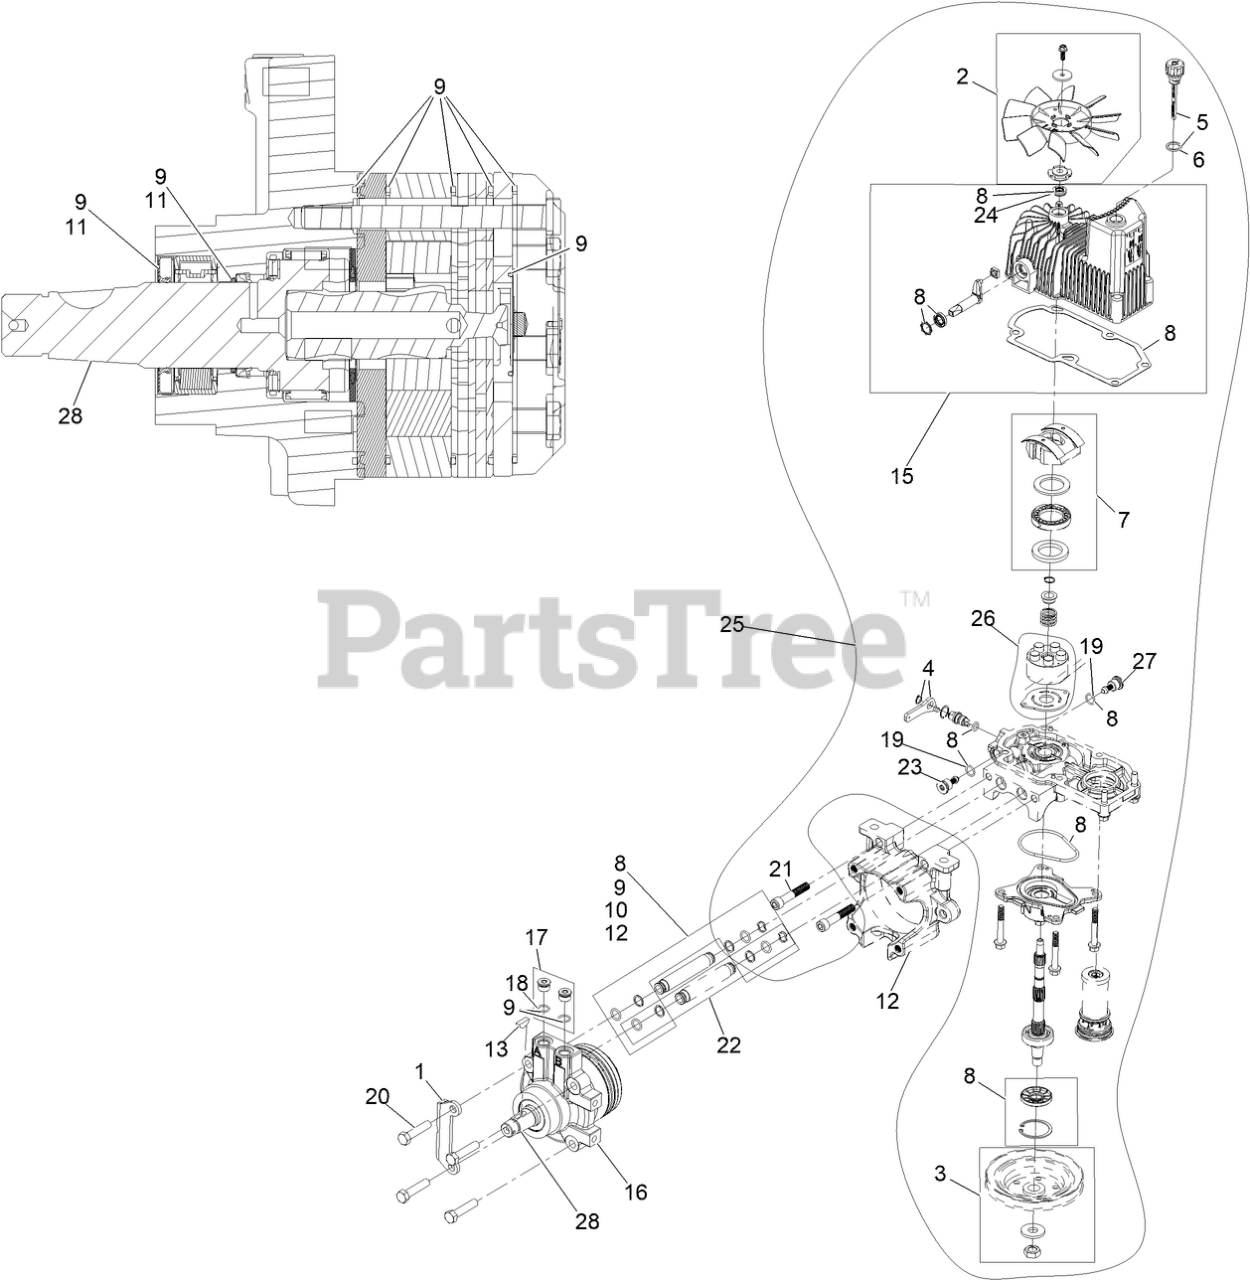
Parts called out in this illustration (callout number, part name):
1	PLATE, HORSE SHOE MOUNT
2	KIT, 7.8 IN FAN
3	PULLEY KIT
4	HANDLE-BYPASS VALVE, HYDRO
5	DIPSTICK-HYDRO W/GASKET
6	GASKET-DIPSTICK, HYDRO
7	SWASH BLOCK KIT
8	KIT, PUMP SEAL
9	MOTOR SEAL KIT
10	TUBE SEAL KIT
11	OUTPUT SHAFT SEAL KIT
12	NOSE CUP-UHT
13	KEY-WOODRUFF
15	KIT, HOUSING-HYDRO RH
16	MOTOR-HYDRAULIC RH 240CC
17	MAGNETIC PLUGS SERVICE KIT
18	O-RING
19	O-RING-CHECK VALVE
20	SCREW HH
21	SCREW-HSH
22	HYDRAULIC TUBE KIT
23	SHOCK VALVE, 12CC HYDRO
24	SEAL-FAN DRIVE
25	KIT, PUMP SECTION 12CC RH
26	KIT - 12CC PORT PLATE,ROTATE GRP
27	SHOCK VALVE ORIFICED 3800
28	OUTPUT SHAFT- TL UHT MOTOR
